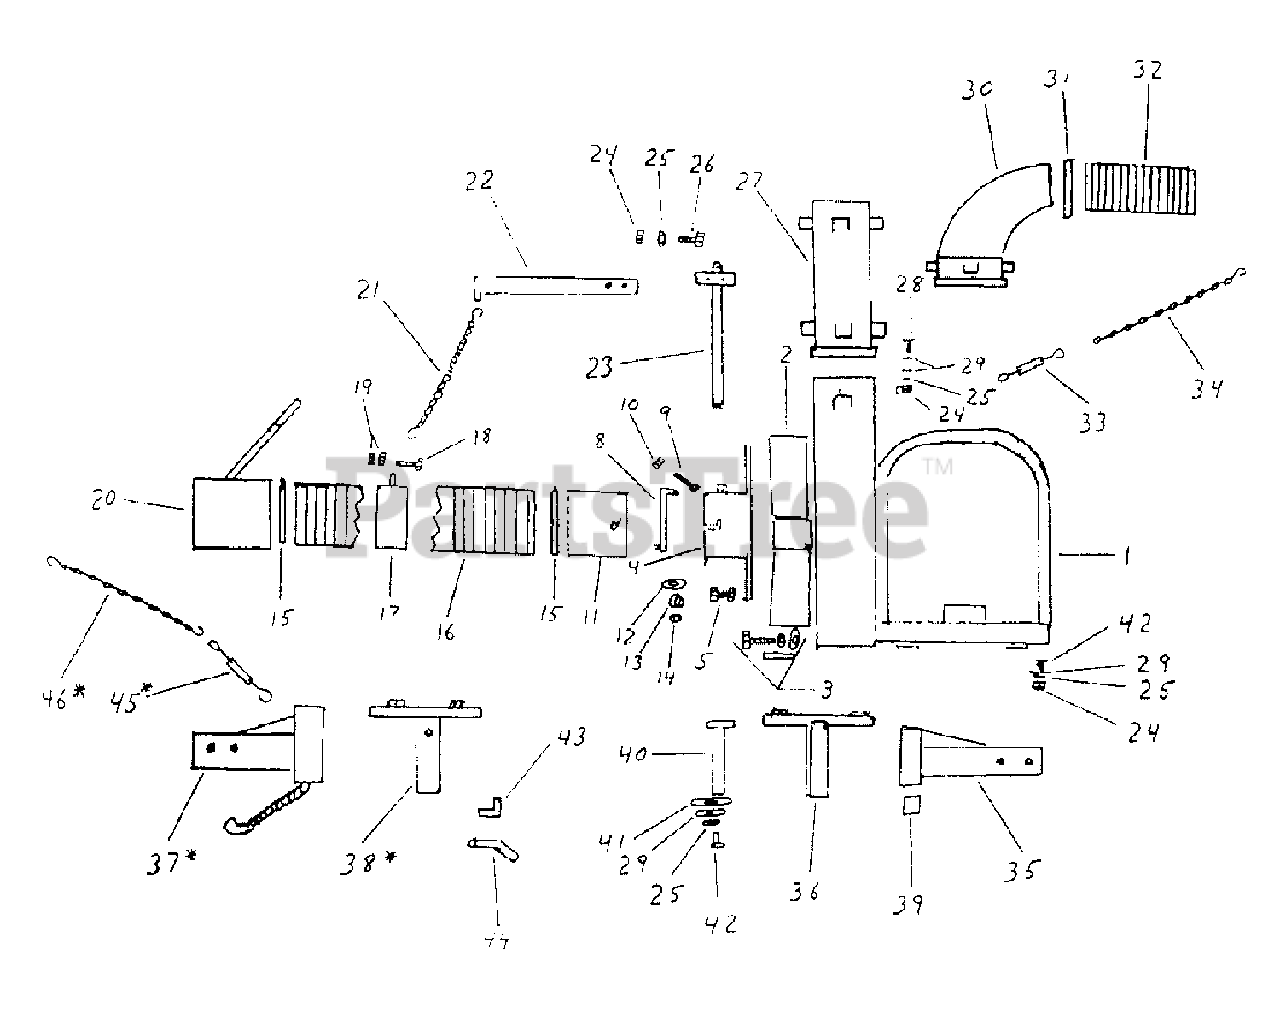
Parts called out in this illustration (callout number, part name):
1	Motor Base & Housing
3	7/16-20 x 2 Impeller bolt, Washers & Key Kit
4	Intake Flange 10"
5	5/16 x 3/4 Hex Bolt & Lock Washer
8	Intake Flange Safety Cover 10"
9	1/2 x 2-1/2 Hex Bolt
10	1/2 Lock Nut
11	Quick-Release Hose Adapter 10"
12	5/16 Fender Washer
13	5/16 Plastic Knob Nut
14	5/16 Lock Nut
15	10" Hose Clamp
16	10" x 10' Intake Hose
17	10" Support Band
18	5/16 x 3-1/2" Hex Bolt
19	5/16 Nut
20	Intake Nozzle 10" w/Adj Handle
21	Boom Chain
22	Upper Boom Support
23	Lower Boom Support
25	1/2 Lock Washer
26	1/2 x 1" Hex Bolt
27	Discharge Stack
28	1/2 x 4-1/2" Hex Bolt
29	1/2 Flat Washer
30	Discharge Elbow
31	7" Squeeze Ring
32	7" x 30" Metal Discharge Hose
33	3/8 x 7-1/2" Turnbuckle
34	Upper Body Support Chain
35	Standard Swing Arm - Vehicle Side
36	Standard Swing Arm - Unit Side
37	Long Swing Arm - Vehicle Side
38	Long Swing Arm - Unit Side
39	Swing Arm Bushing
40	Swing Arm Pivot Pin
41	5/8 Flat Washer
42	1-1/4" Single Split Collar
43	Swing Arm Locking Bracket
44	5/8-11 Handle
45	3/8 x 7-1/2" Turnbuckle
46	Boom Chain (Secondary Safety Chain Long Arm)
